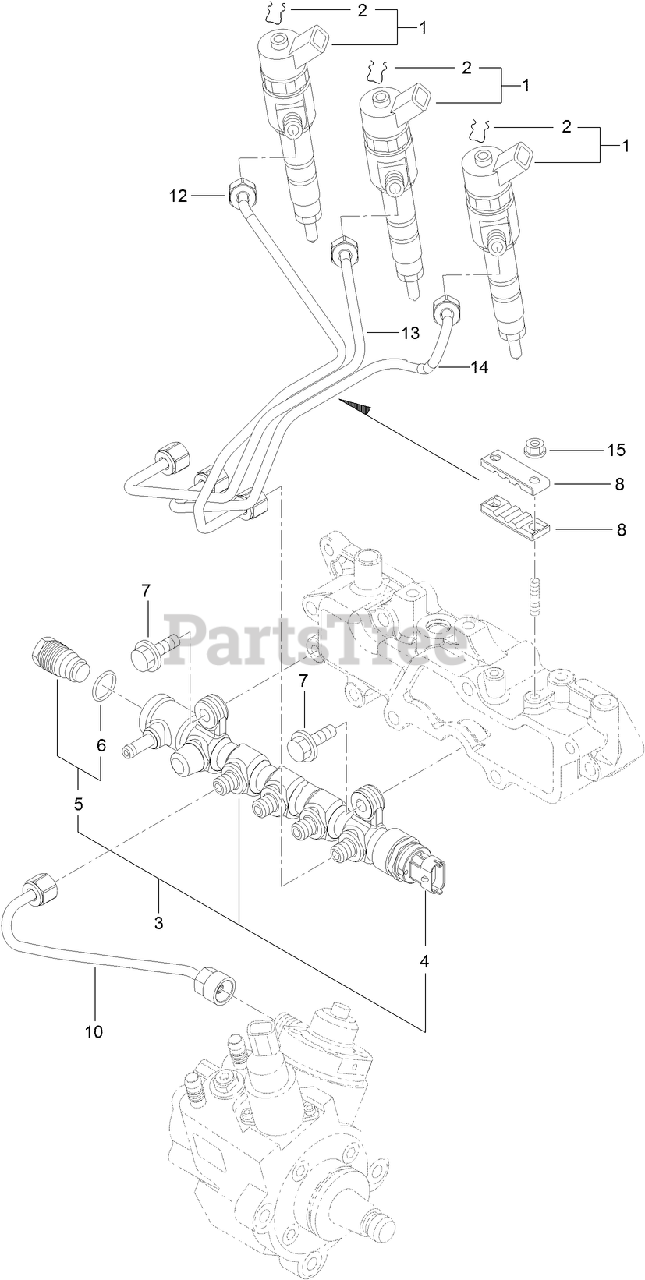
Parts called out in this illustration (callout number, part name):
1	INJECTOR ASM
2	RING-RETAINING
3	RAIL ASM
4	SENSOR-PRESSURE, RAIL
5	VALVE ASM
6	O-RING
8	RETAINER
10	RAIL IN PIPE ASM
12	INJECTION PIPE ASM
13	INJECTION PIPE ASM
14	INJECTION PIPE ASM
